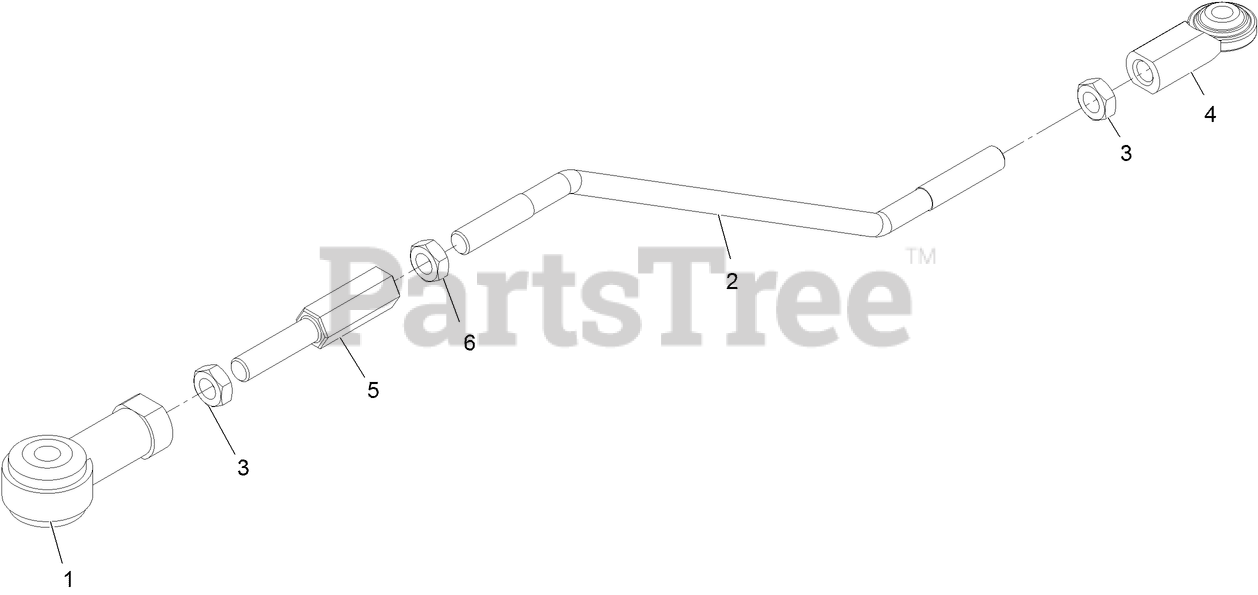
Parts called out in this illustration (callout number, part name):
1	END-ROD, ISOLATED
2	ROD-LINKAGE, REAR
3	NUT-HJ
4	JOINT-BALL, END
5	ROD-ADJUSTMENT
6	NUT-HEX JAM, LH
